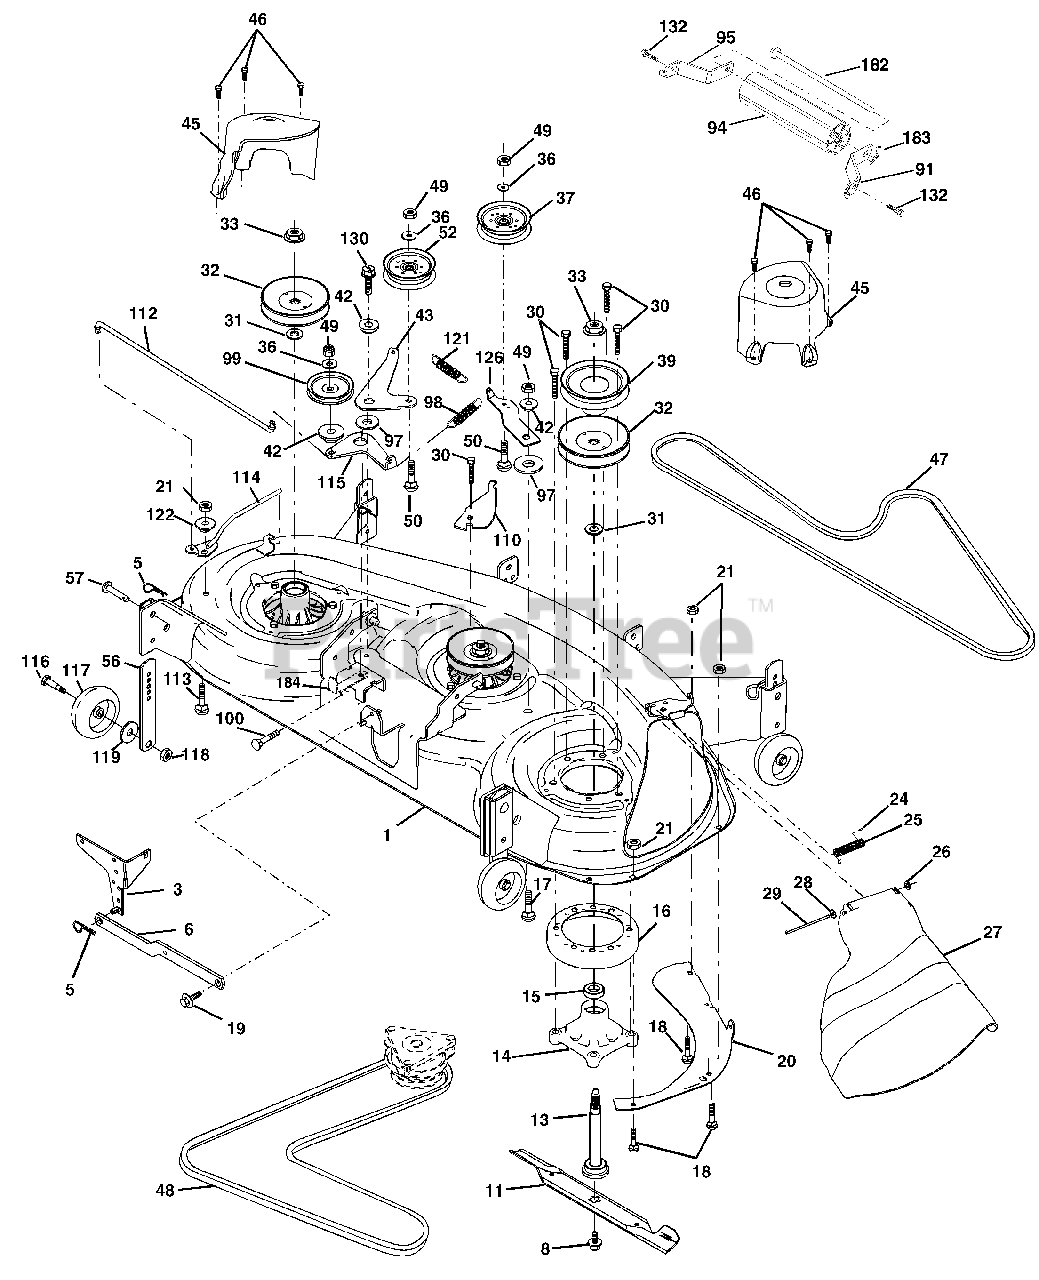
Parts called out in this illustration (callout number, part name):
1	Deck Weldment Mower 48
3	Bracket Asm., Sway Bar
5	Retainer Spring
6	Sway Bar Deck
8	Bolt 7/16 Asm. Blade
11	Blade, 48" Mulching
11	Blade, 48" Hi-lift
13	Shaft Asm. w/Lower Bearing
14	Mandrel Asm.
15	Bearing, Ball, Mandrel
16	Stripper Mandrel Deck
17	Bolt RDHD Sq Neck 3/8-16 x 1.25
18	Bolt, Carriage 5/16-18 x 5/8
19	Bolt, Hex Hd, Shoulder 5/16-18
20	Baffle, Vortex Mower
21	Nut, Crownlock 5/16-18 Unc
24	Cap, Sleeve
25	Spring, Torsion
26	Nut, Push
27	Deflector Shield
28	Washer 11/32 x 5/8 x 16 Ga.
29	Rod, Hinge
30	Screw, Thdroll Washer Head
31	Washer, Spacer Mower Vented
32	Pulley, Mandrel
33	Nut, Flg. Top Lock Cntr. 9/16
36	Washer 13/32 x 13/16 x 16 Ga.
37	Pulley, Idler, Flat
39	Pulley, Idler, Driven
42	Spacer, Retainer
43	Arm, Idler Secondary
45	Cover, Mandrel Deck
46	Screw, Thdroll. 1/4-20 x 5/8
47	V-Belt, Mower, Secondary
48	V-Belt, Mower, Primary
49	Nut, Crownlock 3/8-16 Unc
50	Bolt, Carr. 3/8-16 x 1-1/2 Gr. 5
52	Pulley Idler Flat
56	Bar Pnt Adj.
57	Pin Head Rivet
91	Bracket Asm N Roller RH
94	Roller Nose 48"
95	Bracket Asm N Roller LH
97	Washer Hardened
98	Spring Primary Drive
99	Pulley Idler "V"
100	Bolt RDHD Sqnk 3/8-16 Unc x 2
110	Arm Spring Secondary
112	Link Tension Relief Lever
113	Bolt Carr. 5/16-18 x 3/4
114	Tension Asm. Relief Lever
115	Arm Spring Tension Relief
116	Bolt, Shoulder
117	Gauge Wheel
118	Nut, Centerlock 3/8-16 Unc
119	Washer 3/8 x 7/8 x 14 Ga.
121	Spring Secondary Drive
122	Bushing Pivot Tension Relief
126	Arm, Idler, Primary Deck
130	Screw 3/8-16 x 1.0
132	Screw 3/8-16 x .75
182	Rod Roller Nose
183	Retainer Spring
184	Keeper Belt Idler
